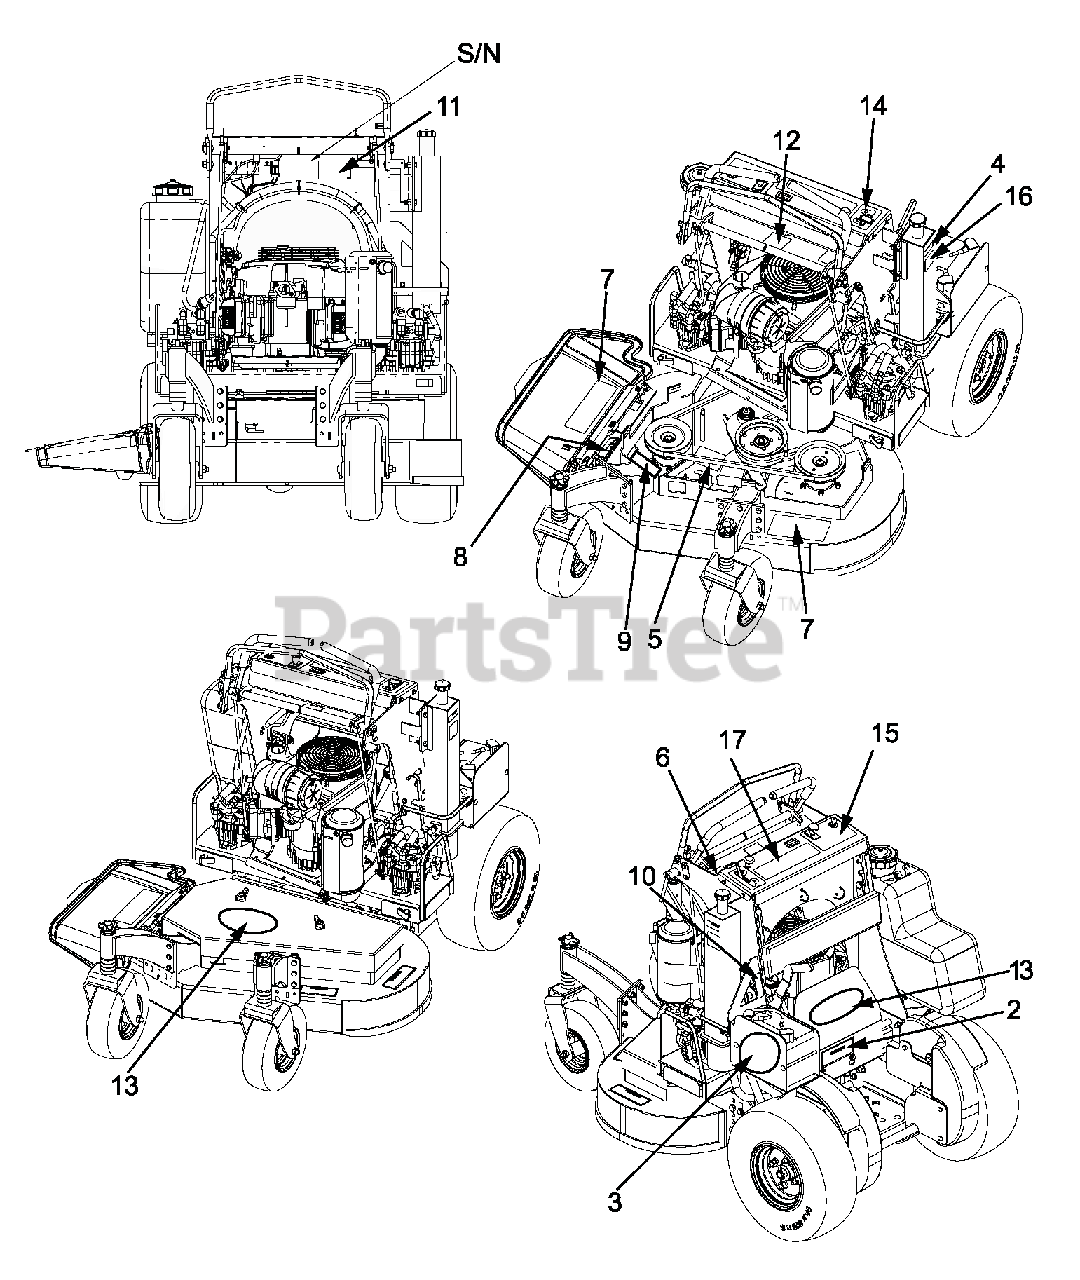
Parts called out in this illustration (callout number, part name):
1	DECAL, PROSTANCE 1934 FX
2	DECAL, DEBRIS
3	DECAL, FX
4	LABEL, WARNING (HOT SURFACES)
5	DECAL, BELT ROUTING
6	DECAL, WARNING - SLOPE
7	DECAL, MOWER PAN DANGER
8	EZT ZERO TURN DECAL SMALL
9	DECAL, WARNING - SHIELD
10	LABEL - PARK BRAKE DIRECTION
11	DECAL, PATENT
12	DECAL, DIRECTIONAL CONTROL
13	MANUAL, OWNERS-GRAVELY BRUSH
14	DECAL, THROTTLE
15	DECAL, PTO & KEY SWITCH
16	DECAL, HYDRO OIL SPECS.
17	DECAL, GENERAL CAUTION
